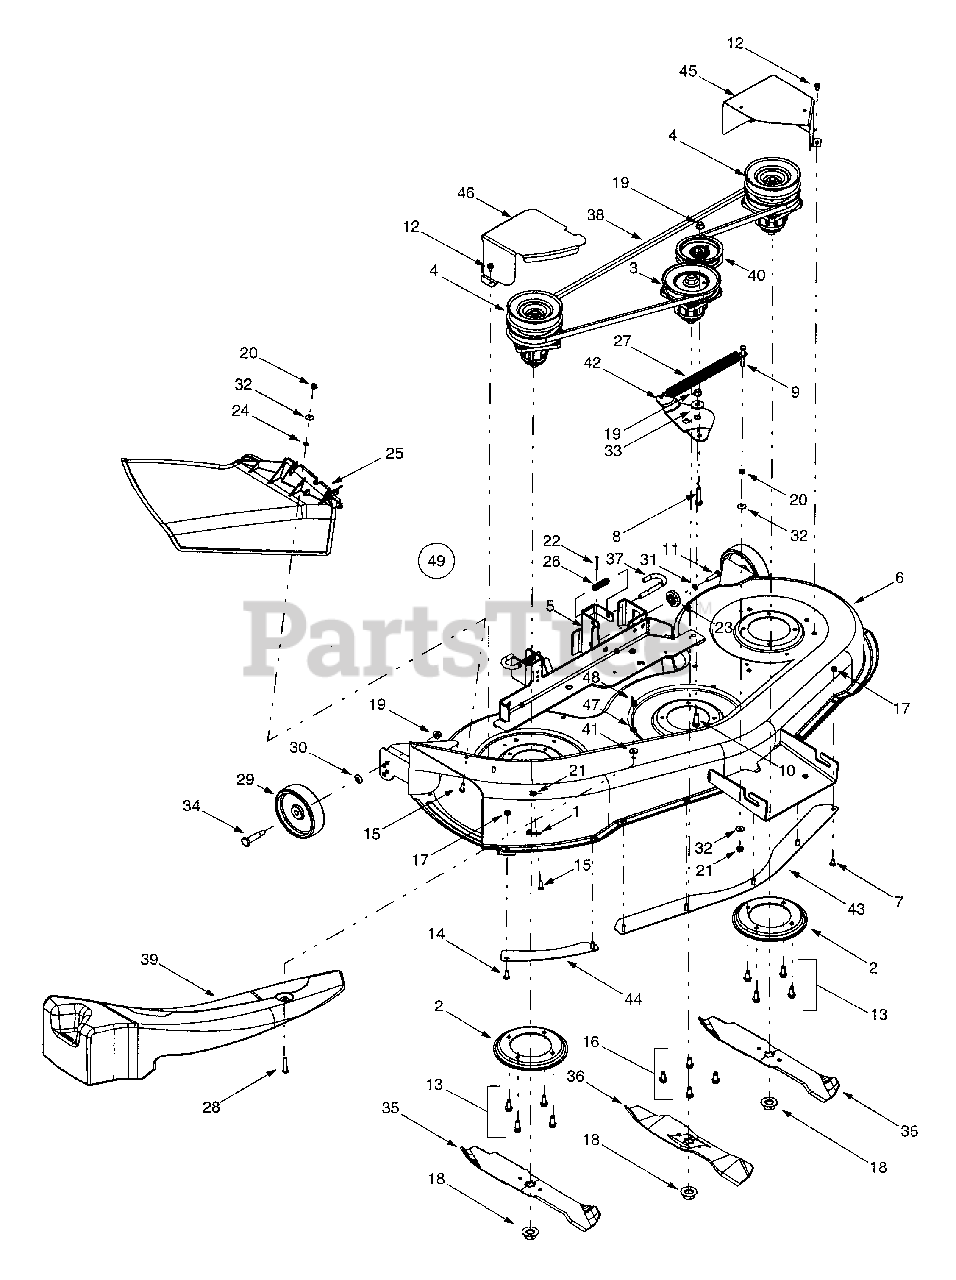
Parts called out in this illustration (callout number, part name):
1	Retainer Hook
4	Double Pulley Spindle Assembly
8	Hex Cap Screw, 3/8-16 x 1.5
9	Hex Cap Screw, 1/4-20 x 2.0
10	Hex Cap Screw, 3/8-16 x 1.0
11	Hex Cap Screw, 5/8-18 x 1.25
12	Self-tapping Screw, 1/4-20 x .5
13	Self-tapping Screw, 15/16-18 x .875
14	Hex Screw, 1/4-20 x .75
15	Hex Cap Screw, 1/4-20 x .62
16	Self-tapping Screw, 5/16-18 x .75
17	Hex Sems Nut, 1/4-20
18	Hex Flange Nut, 5/8-18
19	Flange Lock Nut, 3/8-16
20	Hex Nut, 1/4-20
21	Hex Flange Lock Nut, 1/4-20
22	Cotter Pin, 1/8 x 1.25
23	Deck Adjustment Gear
24	Push Nut. .25 x .5
25	Side Discharge Chute Assembly
26	Compression Spring, .406 x .531 x 1.75
27	Extension Spring, .91 x 7.3
28	Screw, 1/4-20 x 1.5
29	Deck Wheel, 5 x 1.38
30	Bell Washer, .401 x .87 x .063
31	Lock Washer, 5/16
32	Bell Washer, .265 x .75 x .062
33	Shoulder Spacer, .625 x 1.16
34	Shoulder Screw
35	Three-in-one Blade, Star Center, 16.28"
36	Three-in-one Blade, Star Center, 14.88"
37	Deck Release Pin
38	Deck Belt, Poly
39	Mulch Plug
40	Idler Pulley, 3.5
41	Flat Washer, .28 x .74 x .063
48	Wing Nut, 1/4-20
